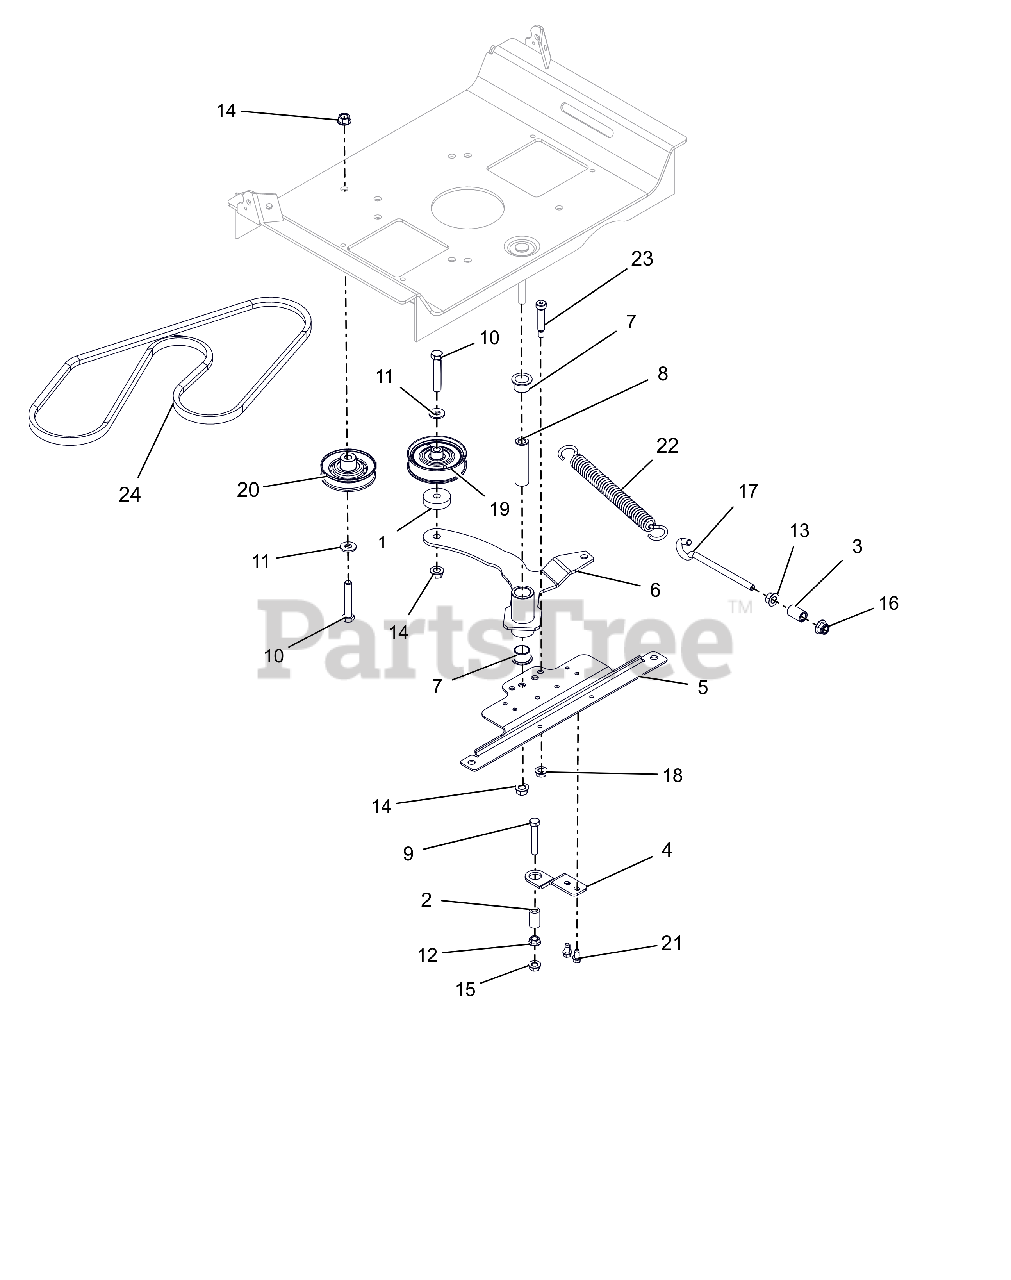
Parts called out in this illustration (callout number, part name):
1	SPACER, .39 X 1.50 X .380
2	SPACER, RUBBER 5/16 IDX1.0 LG
3	SPACER, .375X.625X.970 (PM)
4	BRKT, CLUTCH STOP
5	BRKT, DRIVE IDLER MOUNTING
6	WLDMT,GRD DRIVE IDLER ARM-LGR
7	BSHG-FLG 0.75X0.875X.625X1.125
8	BUSHING, SLEEVE .38X.750X2.78
9	@BLT-HEX .31-18X2.00 GR5 YWZC
10	@BLT-HEX .38-16X2.25 GR5 YWZC
11	@WSHR-FL-STL.38X.875X.083 YWZC
12	@NUT-SPNLK-FLG .312-18 YWZC
13	@NUT-SPNLK-FLG .375-16 YWZC
14	@NUT-LK-TOP-FLG .38-16 YWZC
15	@NUT-LK-TOP-FLG .31-18 YWZC
16	@NUT-LK-NYL-FLG .38-16 YWZC
17	BOLT,.38-16 X 4.25-.62 DIA EYE
18	@NUT-LK-TOP-FLG .31-18 YWZC
19	IDLER, FLAT - 3.05" X .75"
20	IDLER, V-3.000 OD
21	SCR-TAP .25-20X.50 HWH TR YWZ
22	SPRING, EXTENSION
23	BLT-SHLDR .38X1.5X.31-18 SLT Y
24	V-BELT, A-RAW EDGE
